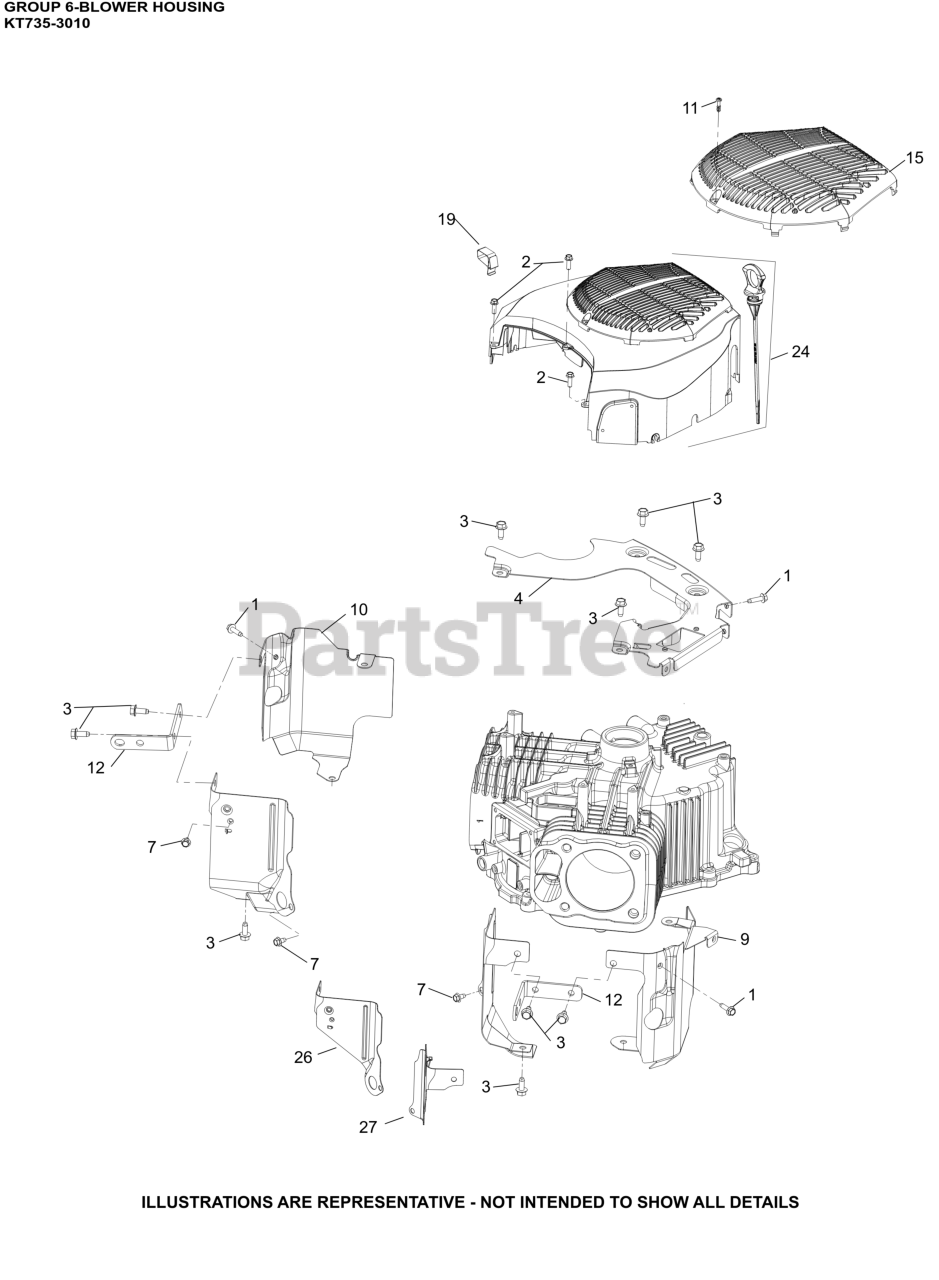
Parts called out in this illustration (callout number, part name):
1	SCREW, THD FRM-USE 25 086 473-S
2	SCREW, HI-LOW
3	SCREW, THREAD FORMING
4	PLATE, BACKING
7	SCREW, THREAD FORMING
9	BAFFLE, LEFT BARREL
10	BAFFLE, RIGHT BARREL
11	SCREW, M5-2.42 (PT) THREAD
12	STRAP, LIFTING
15	GUARD, FIXED
19	CLIP, BLOWER HOUSING
24	KIT, BLOWER HOUSING
26	BAFFLE, VALLEY #1 CYLINDER
27	BAFFLE, VALLEY #2 CYL-USE 32 063 36-S
